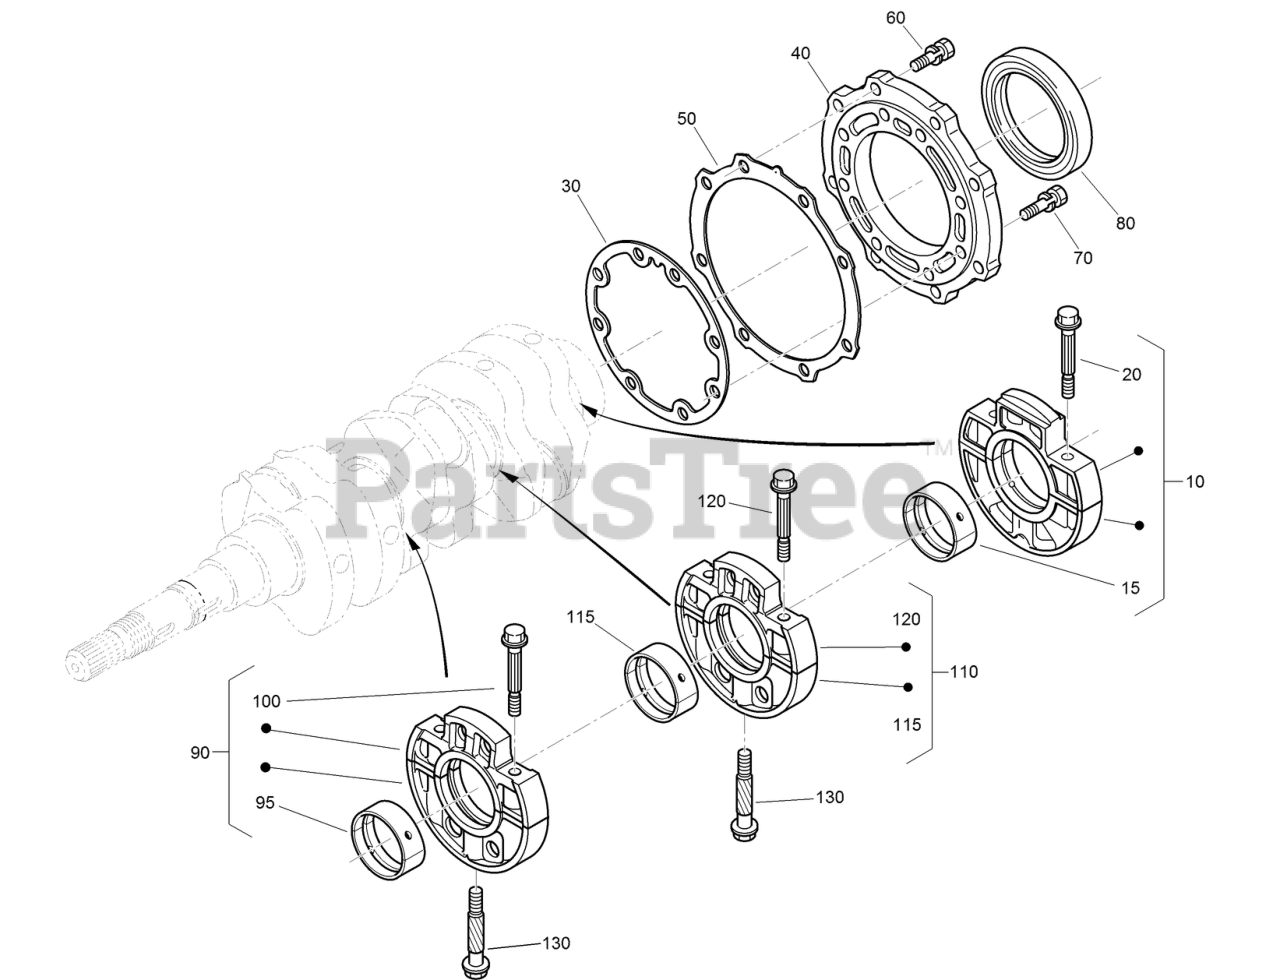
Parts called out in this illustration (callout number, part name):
10	WHEEL BEARING CASE ASM
10	PISTON (05)
15	METAL-CRANKSHAFT
15	METAL-CRANKSHAFT (-0.20MM)
15	METAL-CRANKSHAFT (-0.40MM)
20	BOLT-CASE, BEARING
30	GASKET-CASE, BEARING
40	COVER-CASE, BEARING
50	GASKET-CASE COVER, BEARING
80	SEAL-OIL
90	CASE-BEARING, MAIN
95	METAL-CRANKSHAFT
95	METAL-CRANKSHAFT (-0.20MM)
95	METAL-CRANKSHAFT (-0.40MM)
100	BOLT-CASE, BEARING
110	MAIN BEARING CASE ASM
115	METAL-CRANKSHAFT
115	METAL-CRANKSHAFT (-0.20MM)
115	METAL-CRANKSHAFT (-0.40MM)
120	BOLT-CASE, BEARING
130	BOLT-CASE, BEARING
